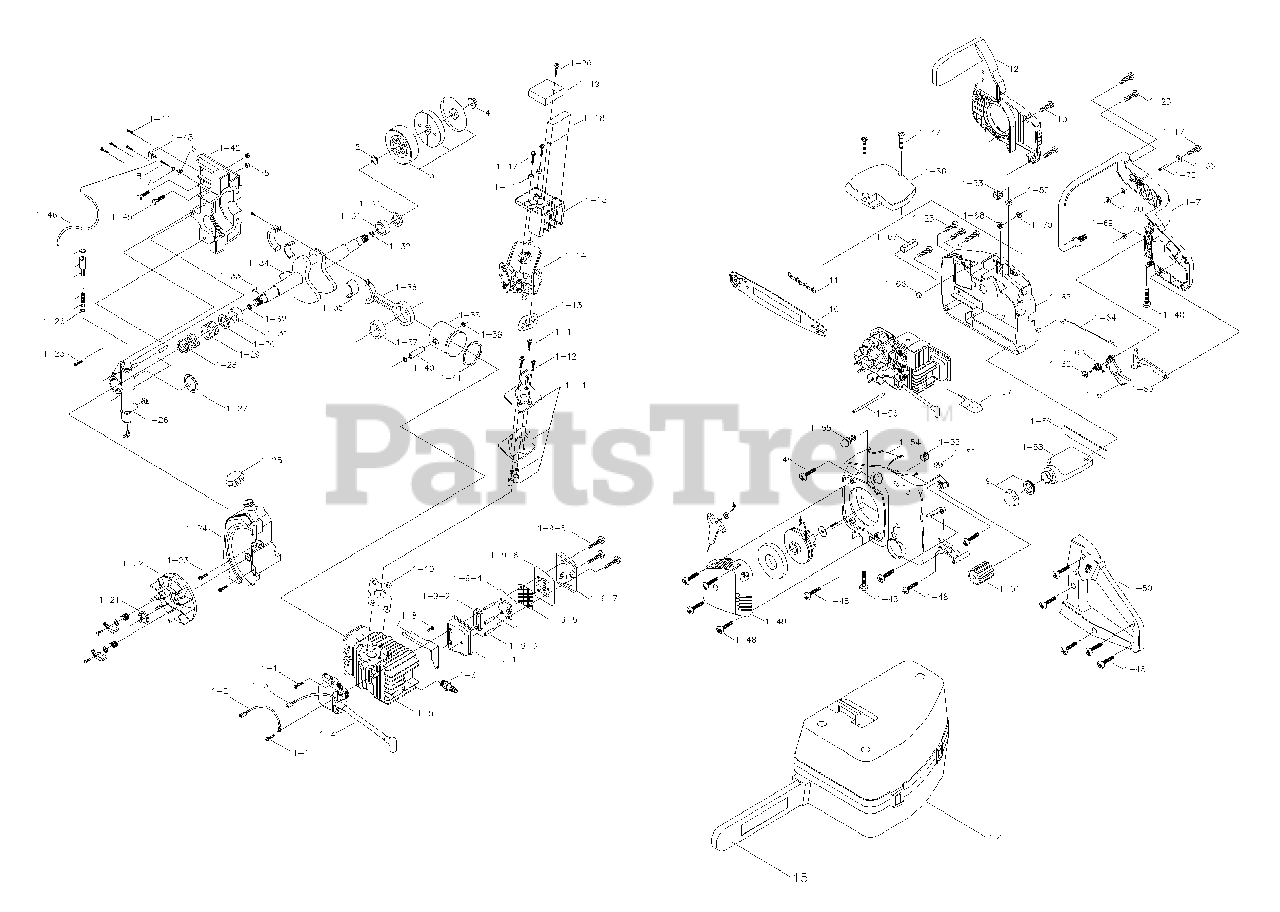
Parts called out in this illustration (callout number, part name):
1	POWERHEAD ASS'Y
1-2	WIRE ASS'Y, GROUND
1-3	WIRE ASS'Y, STOP SWITCH
1-4	IGNITION ASS'Y
1-7	BAFFLE, AIR
1-9	MUFFLER ASS'Y
1-9-1	COVER, MUFFLER
1-9-2	PLATE, REINFORCING
1-9-3	SPACER, MUFFLER
1-9-4	BAFFLE, OUTER
1-9-5	BAFFLER, INNER MUFFLER
1-9-6	SCREEN, SPARK ARRESTER
1-9-7	COVER, MUFFLER
1-10	GASKET, INSULATOR
1-11	INSULATOR ASS'Y
1-14	CARBURETOR
1-15	BOX,AIR FILTER
1-17	SCREW
1-18	FILTER, AIR
1-19	SHIELD,CARBURETOR
1-22	FLYWHEEL ASS'Y
1-24	FUEL TANK ASS'Y
1-25	CAP, FUEL ASS'Y
1-26	OIL PUMP ASS'Y
1-29	WORM GEAR
1-30	SEAL, C'SHAFT OIL
1-34	CRANKSHAFT
1-36	COVER, AIR FILTER
1-38	PISTON
1-41	PISTON RING
1-44	SCREW
1-45	BOLT, BAR
1-49	STARTER HOUSING ASS'Y
1-50	HANDLE ASS'Y, LEFT
1-51	ISOLATOR,RUBBER
1-53	RETAINER,NUT
1-54	ENGINE HOUSING, LEFT
1-57	SLIDE, CHOKE
1-58	OIL TANK ASS'Y
1-59	SPACER, OIL TANK
1-60	LATCH, THROTTLE
1-61	TRIGGER,THROTTLE
1-64	CABLE,THROTTLE
1-65	ENGINE HOUSING, RIGHT
1-66	FILTER, FOAM
1-68	NUT
1-71	HANDLE ASS'Y, RIGHT
3	DRUM ASS'Y
7	RING, RETAINING
9	OIL CAP ASS'Y
12	CHAIN BRAKE ASS'Y
14	CARRY CASE
